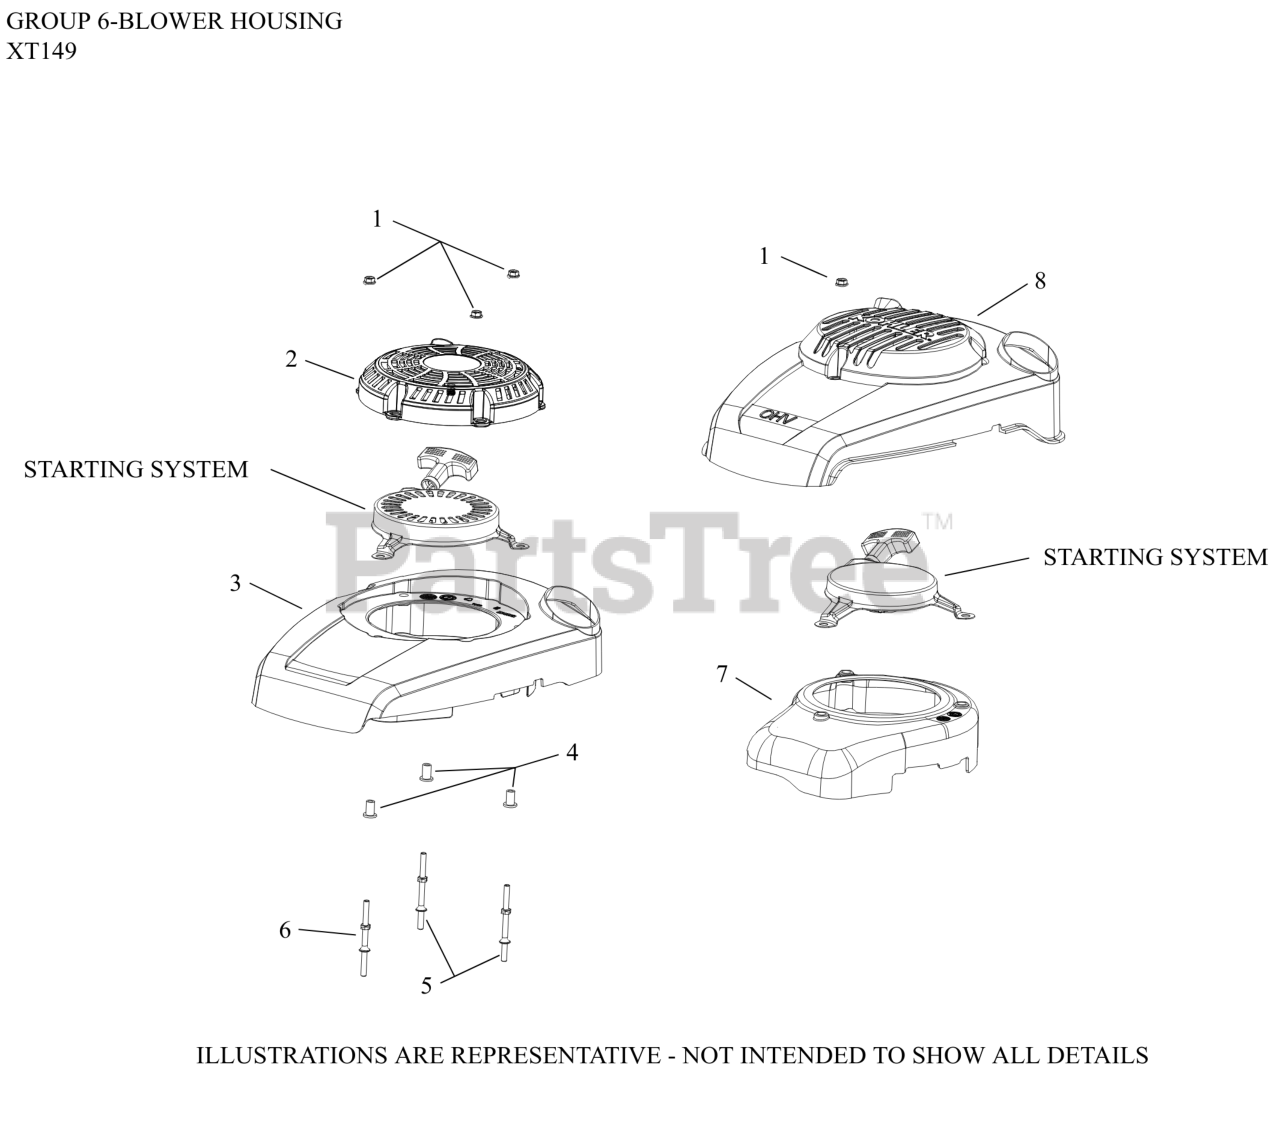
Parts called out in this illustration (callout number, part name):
1	NUT, HEX FLANGE (M6) - USE 14 100 16-S
5	STUD-USE 14 072 26-S
6	STUD-USE 14 072 25-S
7	HOUSING, BLOWER
8	COVER, ENGINE (BLACK)-USE 14 096 58-S
